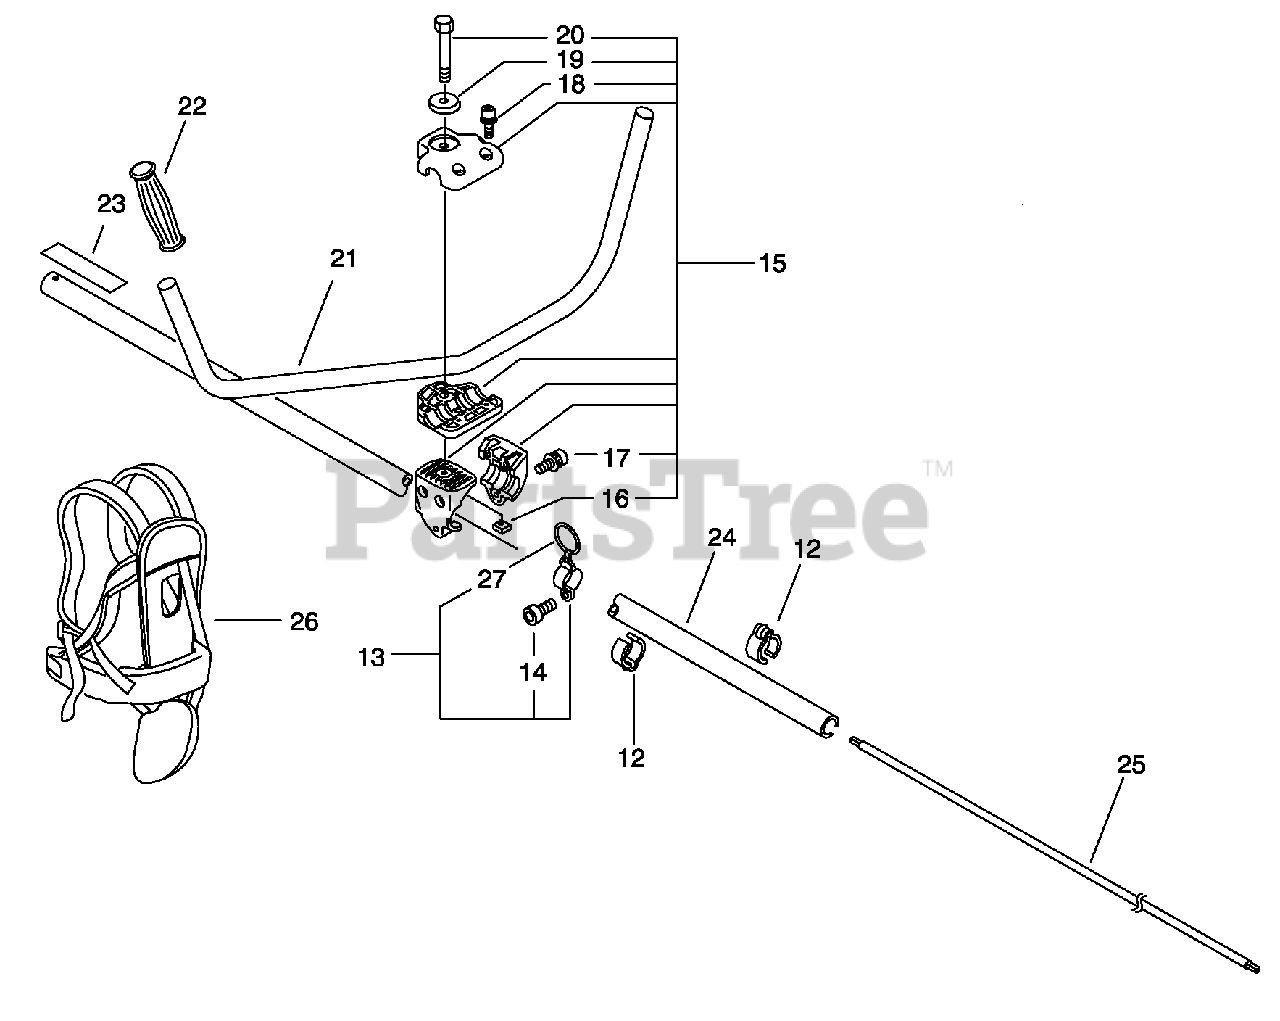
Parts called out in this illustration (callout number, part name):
12	CLIP, CABLE 25 MM
13	HANGER ASSY
14	BOLT 5×12
15	BRACKET KIT, HANDLEBAR
16	NUT 8×1.25
17	BOLT 5×30
18	BOLT 5×20
19	WASHER 8
20	BOLT 8×55
21	HANDLEBAR
22	GRIP, HANDLE
23	LABEL, CAUTION - ISO
24	MAIN PIPE ASSY 25×L= 1500
25	DRIVESHAFT
26	HARNESS, SHOULDER
27	RING, HARNESS
